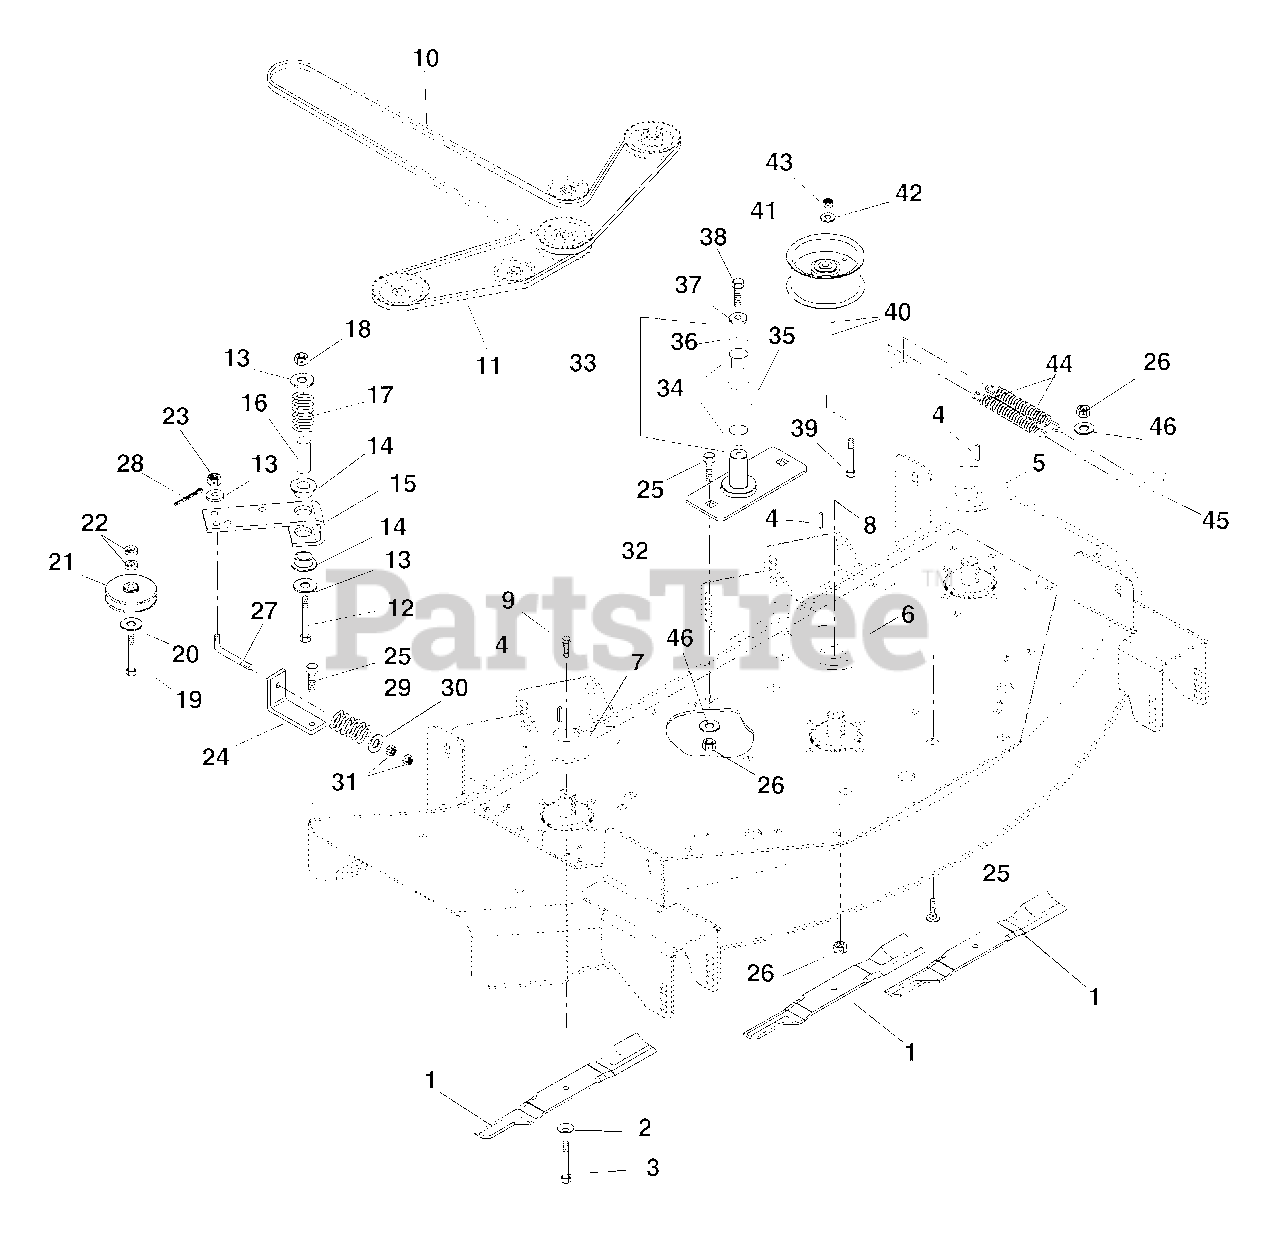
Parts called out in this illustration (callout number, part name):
1	BLD, 50 INCH MOWER
2	WSHR-BLVL .669X1.535X.138
3	BLT-HEX .62-18X1.50 GR8 YWZC
4	KEY-SQ .25X1.0X.25 SAE 8630
5	WLDM'T,PLY-V 4.75X1.004
6	WLDM'T PLY-DBLV 4.75,3.50X1.00
7	WLDM'T, PLY-V 3.50X1.004 W/KEY
8	WASHER, CUPPED SERRATED, .375
9	BLT-HEX .38-16X1.00 YZ GR8
10	V-BELT, A-RAW EDGE
11	V-BELT, HA-RAW EDGE
12	@BLT-RDHDSQNK .50-13X3.50 G5YZ
13	WSHR-FL-STL .531X1.250X.10 YWZ
14	BSHG-FLG .762X1.0X.580X1.48 NY
15	ARM,IDLER PIVOT
16	SPACER .560X.750X2.437 ST
17	SG-COMP .085X.80X1.00 WLD36
18	@NUT-LK-CTR .50-13 YWZC
19	@BLT-HEX .38-16X2.00 GR5 YWZC
20	WSHR-FL-STL .375X1.125X.065YWZ
21	IDLER-V 3X.38
22	BUSHING .406 X .750 X .188
23	@NUT-LK-NYL .38-16 YWZC
24	BRKT,BELT TENSIONER
25	@BLT-HEX .50-13X1.25 GR5 YWZC
26	@NUT-LK-CTR .50-13 YWZC
27	ROD,IDLER
28	@PIN-CTR .09X.75 EXTPRSQCT YWZ
29	SG-COMP .125X.78X1.00 YWZ
30	@WSHR-FL-STL.406X.812X.065 YWZ
31	NUT-HEX-JAM .375-16 YWZC
32	WMT, IDLER PIVOT
33	ASSEMBLY, IDLER PIVOT ARM
34	BRG. 1.000 X 1.125 X .75
35	ASSEMBLY, IDLER PIVOT ARM
36	WSHR-FL-STL .380X1.50X.125YWZC
37	@WSHR-LK .38X.094 REG YWZC
38	BLT-HEX .38-16X1.00 YZ GR8
39	@BLT-HEX .38-16X2.75 GR5 YWZC
40	BUSHING .406 X .750 X .188
41	IDLER-FLAT 4.00X.38 (2.00 W)
42	WSHR-FL-STL .375X1.125X.065YWZ
43	@NUT-LK-CTR .38-16 YWZC
44	SG-EXT-.090X1.00X6.00
45	BRACKET, IDLER SPRING
46	@WSHR-FL-STL.50X1.25X.083 YWZC
